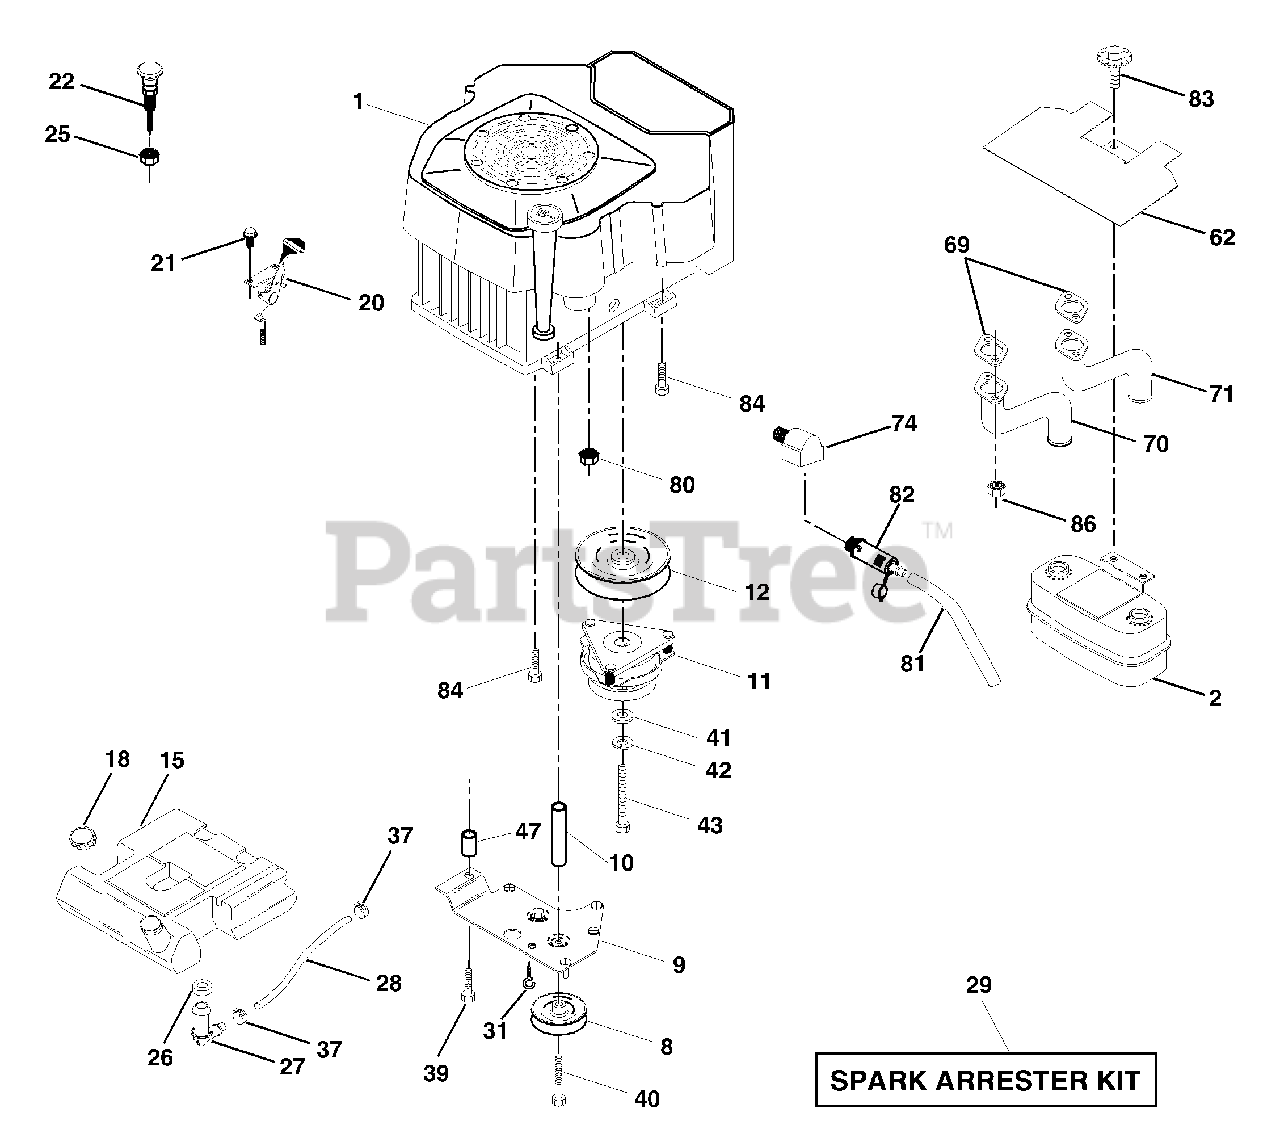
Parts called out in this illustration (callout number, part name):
2	Muffl er Side
8	Pulley V-Idler
9	Keeper Asm. Belt Engine VGT
11	Clutch Electric
12	Pulley Engine VGT Elect Clutch
15	Tank Fuel Rear 5.0
18	Cap Fuel
20	Control Throttle
21	Screw Hwhd Hi-Lo #13-16 x 3/4
22	Control Choke
25	Nut Keps 3/8-24
26	Bushing
27	Stem Tank Fuel
28	Fuel Line
29	Spark Arrester Kit
31	Clip Push-In Hinged
37	Clamp Hose
39	Screw TT 3/8-16 x 2-1/4 unc
40	Screw TT 3/8-16 x 4 unc
41	Washer 1-1/2 OD X 15/32 ID X .250
42	Washer Lock 7/16
43	Bolt Hex 7/16-20 X 3.75 Ga. 5
62	Shield Heat Muffl er
70	Tube Exhaust LH
71	Tube Exhaust RH
74	Elbow Street Brass
80	Nut Flange M8-1.25
81	Oil Drain Tube
82	Plug Drain Oil
83	Bolt 5/16-18 unc x 1-3/4 W/Sems
84	Screw 3/8-16 x 1-1/2
86	Nut Hex Flange Toplock M8-1.25
